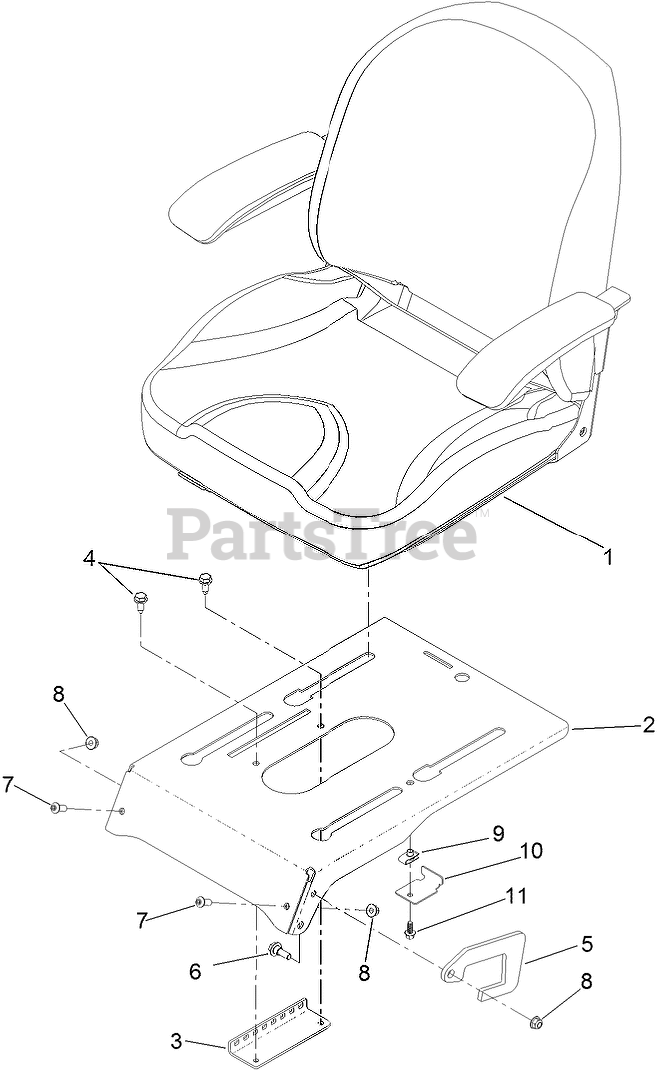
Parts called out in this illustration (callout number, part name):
1	SEAT ASM
2	PAN-SEAT
3	BRACKET-LATCH, SEAT
4	SCREW-HWHTF
5	PLATE-STOP
6	SCREW-SHOULDER
7	SCREW-HSBH
8	NUT-HF, NI
10	BRACKET-STOP, SEAT
11	SCREW-HHF
